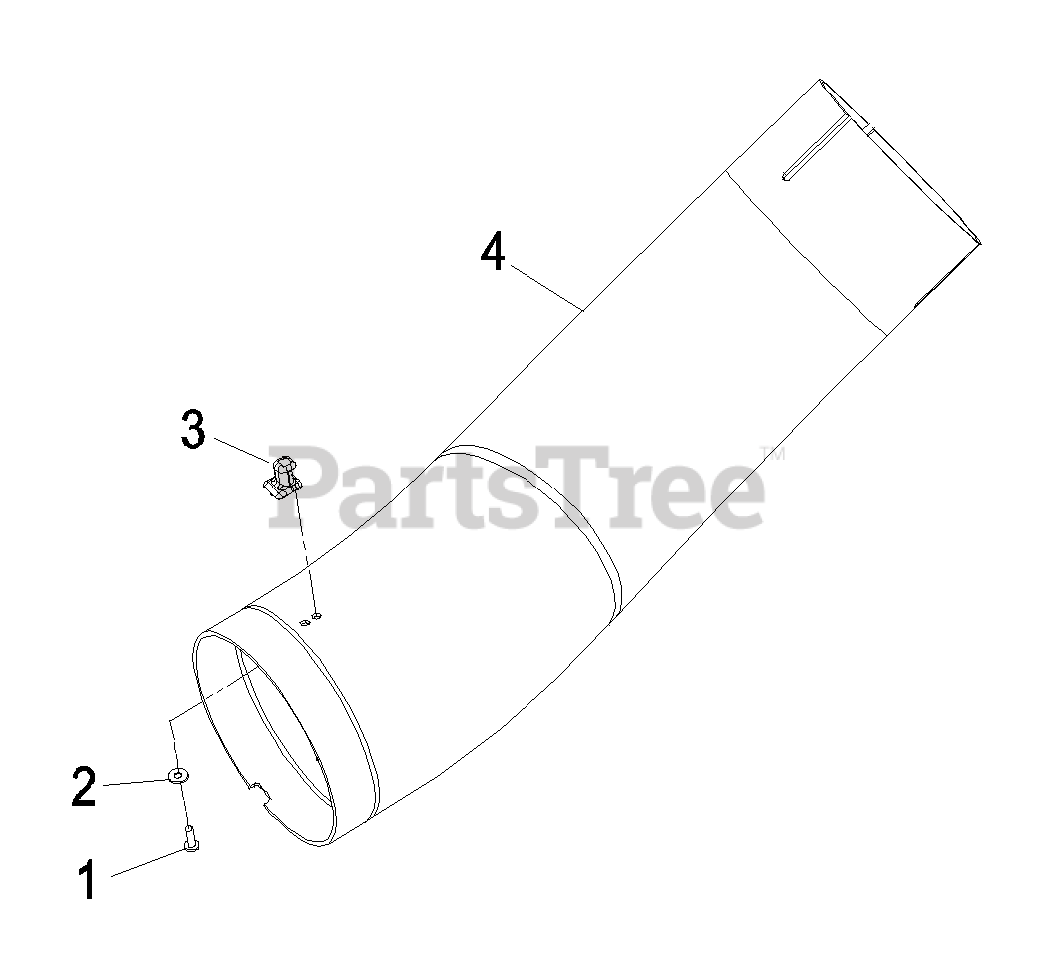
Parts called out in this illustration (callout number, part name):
1	SCREW-PPH
2	WASHER-FLAT
3	LATCH-KEEPER
4	Tube, Lower Short
